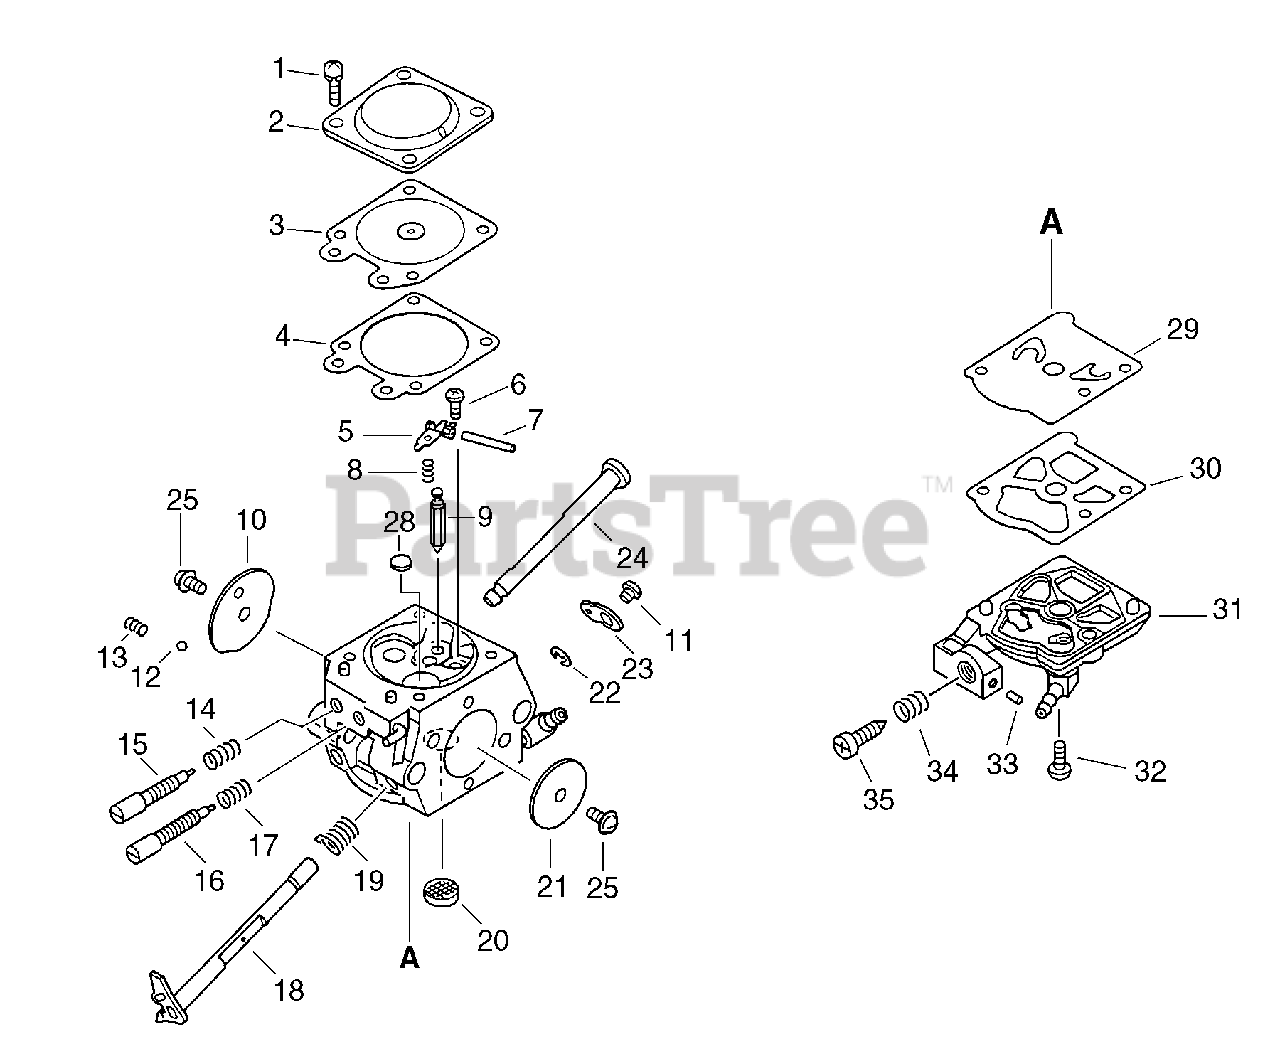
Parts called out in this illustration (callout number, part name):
2	COVER, METERING
3	DIAPHRAGM, METERING
4	GASKET, METERING
5	LEVER, METERING
6	SCREW, METERING LEVER PIN
7	PIN, METERING LEVER
8	SPRING, METERING LEVER
9	VALVE, INLET NEEDLE
10	VALVE, CHOKE
12	BALL, CHOKE
15	NEEDLE - HIGH SPEED
16	NEEDLE - LOW SPEED
18	SHAFT, THROTTLE
19	SPRING, THROTTLE RETURN
20	STRAINER
21	VALVE, THROTTLE
22	RING, RETAINING
23	LEVER, THROTTLE
24	SHAFT, CHOKE
28	PLUG, WELCH
29	DIAPHRAGM, PUMP
30	GASKET, PUMP
31	COVER, PUMP
32	SCREW, PUMP COVER
34	SPRING, IDLE ADJUST
35	SCREW, IDLE ADJUST
